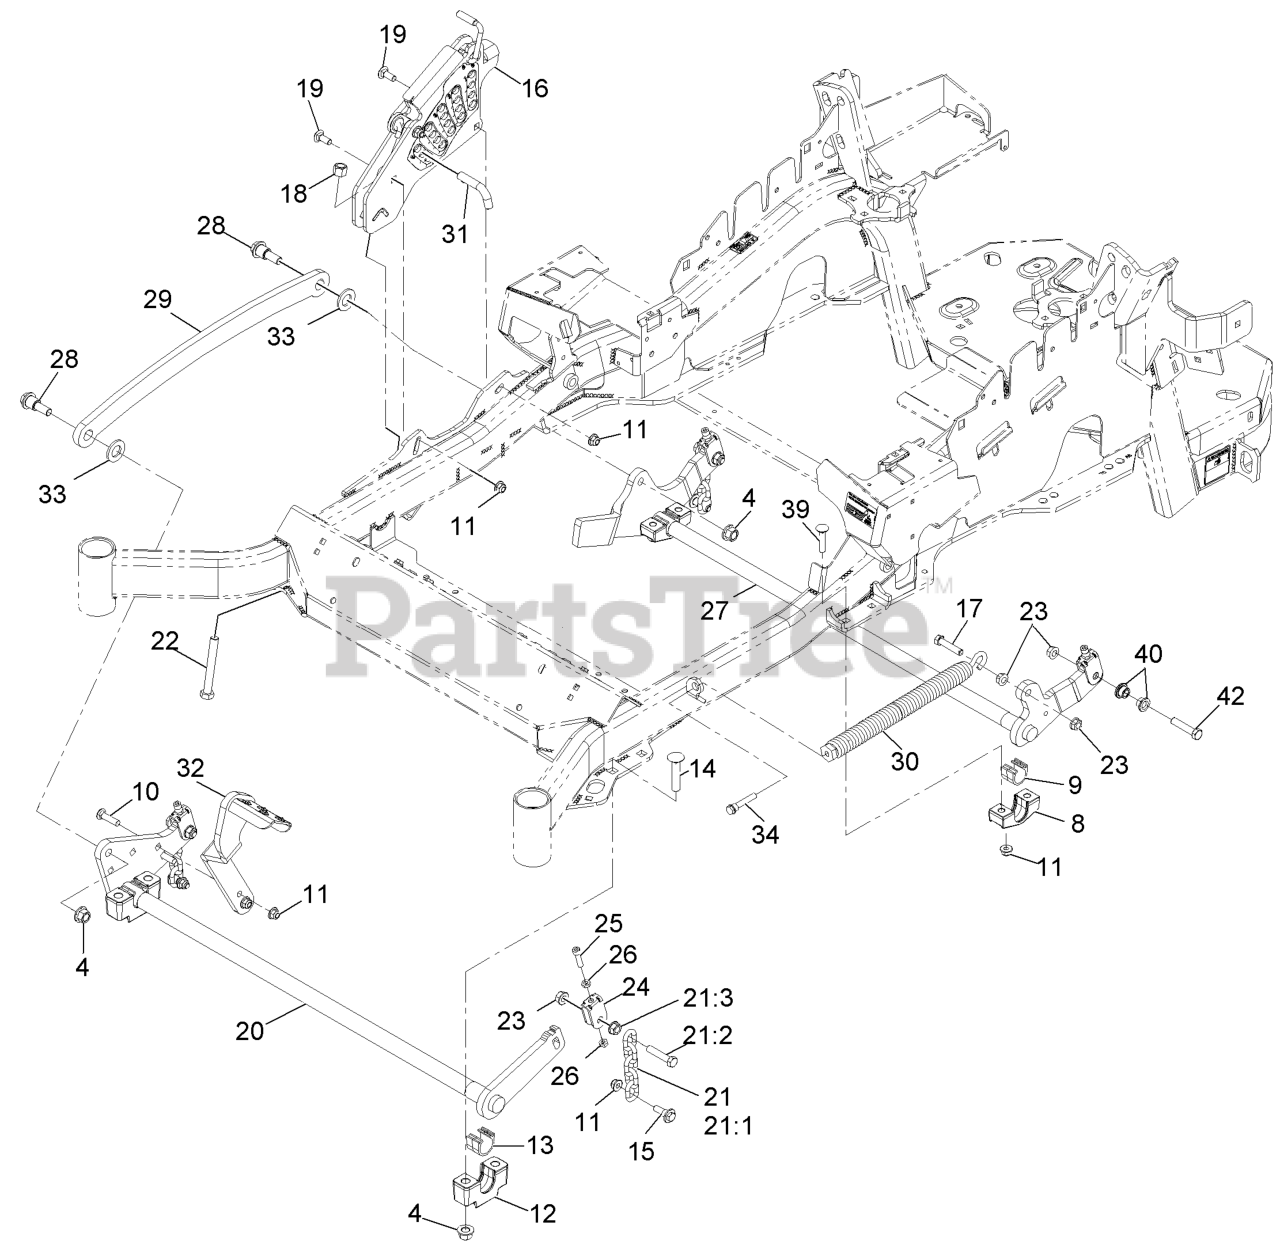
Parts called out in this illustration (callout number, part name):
4	Nut-Lock 1/2-13
9	BEARING-CROSS SHAFT, REAR
10	SCREW-CARR
11	NUT-HF, NI
12	SUPPORT-CROSS SHAFT, BEARING
13	BEARING-CROSS SHAFT, FRON
14	Bolt-Carriage 1/2-13 X 2 1/2 Spl Neck
15	SCREW-SHOULDER, HHF
16	HOC ASM
17	SCREW-HH
18	NUT-LOCK, NI
19	BOLT-CARR
21	DECK LIFT CHAIN ASM
21:1	CHAIN-LIFT, DECK
21:2	SCREW-HH
22	BOLT-TAP
24	YOKE-ADJUST, DECK
25	SCREW-HH
26	NUT-JAM
27	LIFT-DECK, REAR
28	SCREW-SHOULDER, HHF 1/2-13 X 1.12
29	LINK-LIFT, DECK
30	SPRING-EXTENSION
31	PIN-HOC
32	LEVER-FOOT
33	WASHER-FLAT
34	BOLT-SHOULDER
39	SCREW-CARR
40	BUSHING-FLANGED
42	SCREW-HH
